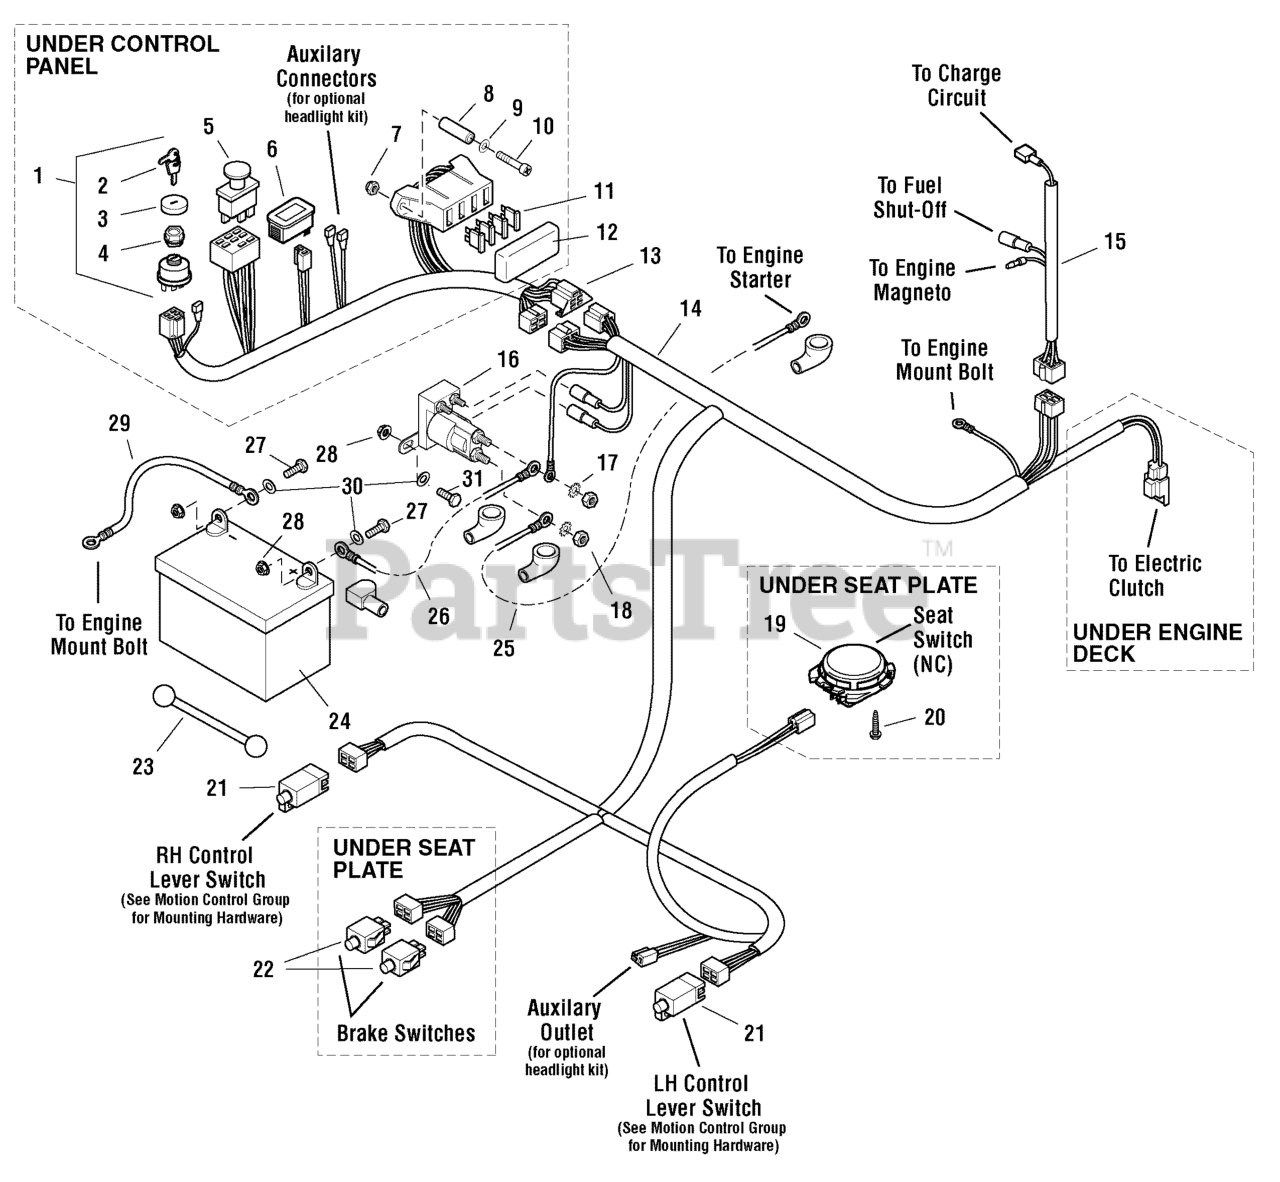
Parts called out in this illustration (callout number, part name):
1	SWITCH, IGNITION, 6 POST
2	KEY, IGNITION MOLDED SET
3	COVER, PLASTIC, SNAP ON
4	PLASTIC NUT
5	SWITCH, BLADE ENGAGEMENT
6	HOURMETER, Digital
7	NUT, #10-24 Hex Nylon Lock
8	SPACER, .20 x .38 x 1.25
9	WASHER, #10 SAE
10	SCREW, #10-24 x 2"
11	FUSE, 20A
12	FUSE BLOCK COVER
13	HARNESS ASSEMBLY, Control Panel
15	ENGINE HARNESS
16	SOLENOID
17	WASHER, Light Lock, 5/16
18	NUT, Hex Jam, 5/16-24
20	BOLT, Hex Washer Head PLASTITE, 1/4 X 1/2
21	SWITCH, PLUNGER, N.O./N.C.
22	SWITCH, DP NO/NC SNAP-IN
23	STRAP, BATTERY, 14 LONG, Rubber
24	BATTERY, Lawn & Garden, 12V (BCIU1, 340 CCA)
25	POSITIVE (+) BATTERY CABLE, 22"
26	POSITIVE (+) BATTERY CABLE, 22"
27	BOLT, 1/4-20 x 3/4
28	NUT, 1/4-20 HEX SERR. FLANGE
29	BATTERY CABLE, NEG, 22, 1/4-5/16
30	WASHER, 1/4 SAE
31	HHCS, 1/4-20 X 0.625, GR5, ZINC/CLEAR
